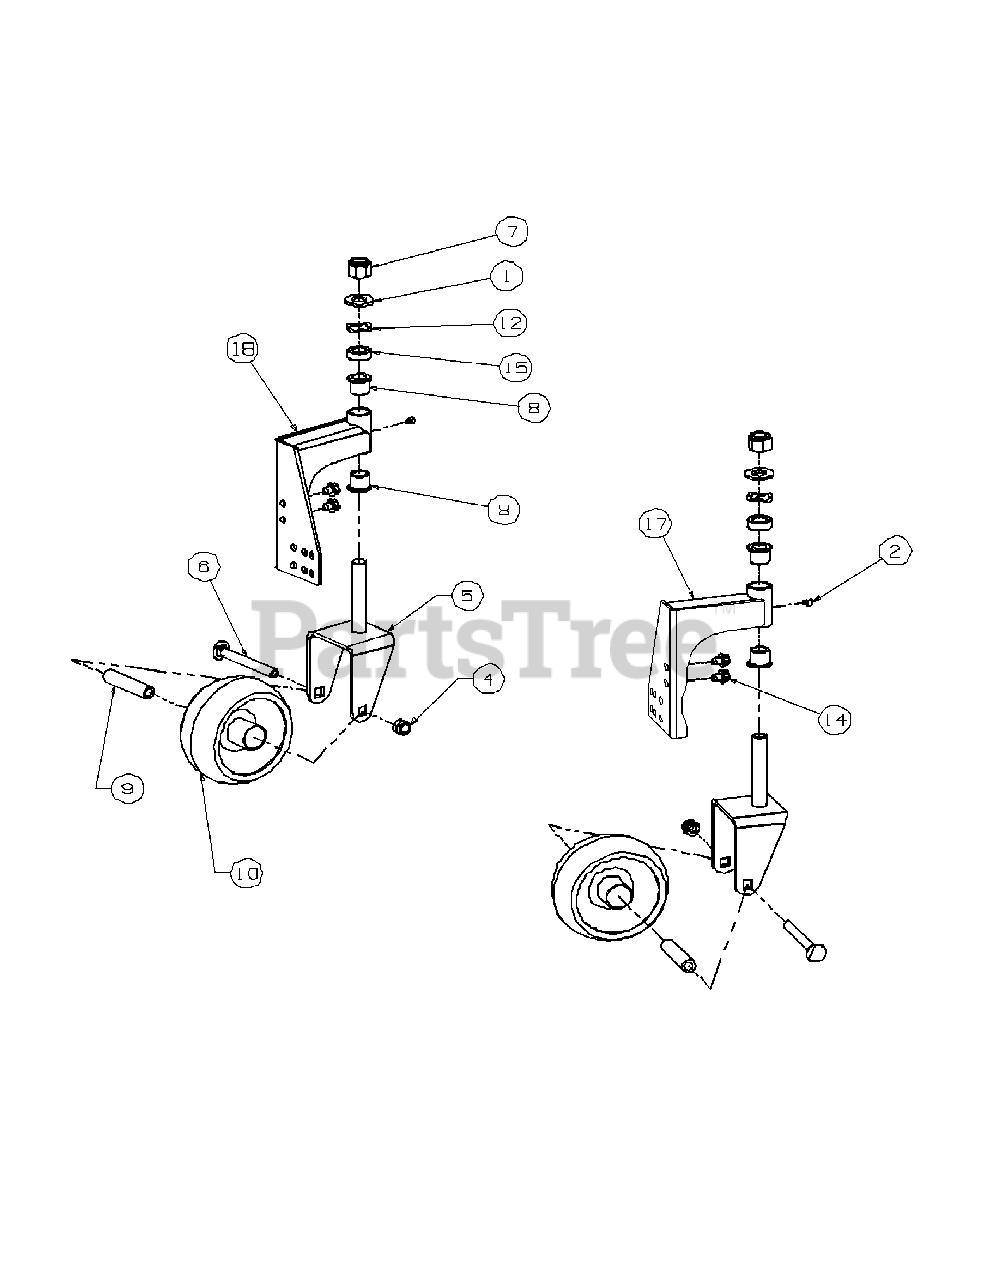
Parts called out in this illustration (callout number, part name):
1	WASH:FL:.750 X 1.50 X .120 THK
2	FTG:GRS:1/4-28 X 3/16 STR
4	NUT:HX:1/2-13:GR5
5	YOKE ASM:CSTR WHL
6	SCR:CARR:1/2-13 X 4.50:GR5
7	NUT:HX:3/4-10:GR5:LOCK
8	BRG:FLG:.754 ID X 1.00 OD X .925
9	AXLE:CSTR WHL
10	WHL ASM:6.25 X 3.00-4:WHITE
12	WASH:WAVE:1.38 OD X .88 ID X .02
14	SCR:TT:3/8-16 X .500:HXINDWSH
15	SPCR:.76 ID X 1.25 OD X .44 LG
17	ASM:LH DECK CSTR BRKT
18	ASM:RH DECK CSTR BRKT
